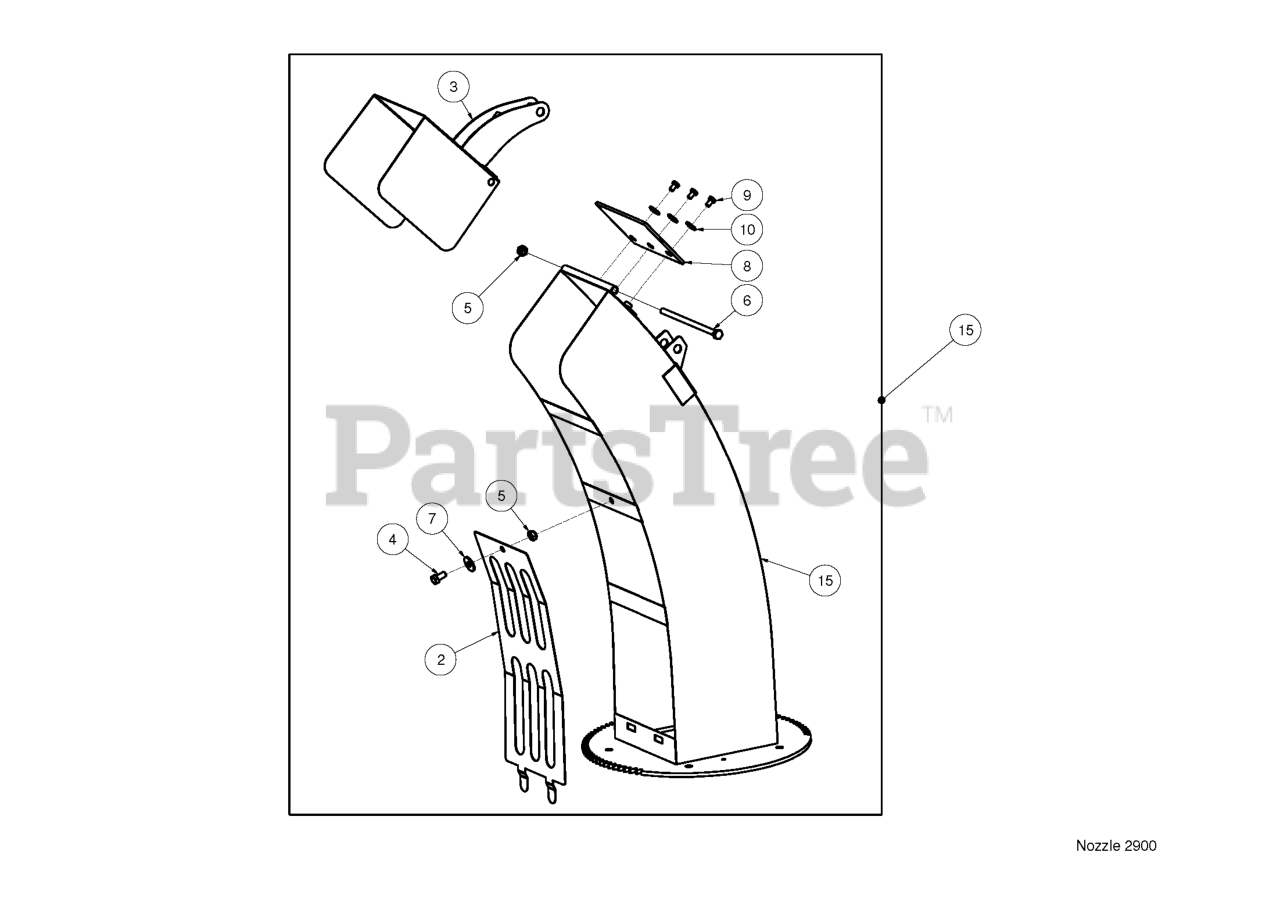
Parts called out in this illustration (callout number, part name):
2	HAND GUARD
4	BOLT - M8X16
5	LOCKNUT M8
10	WASHER - 26X6.5X1.6
